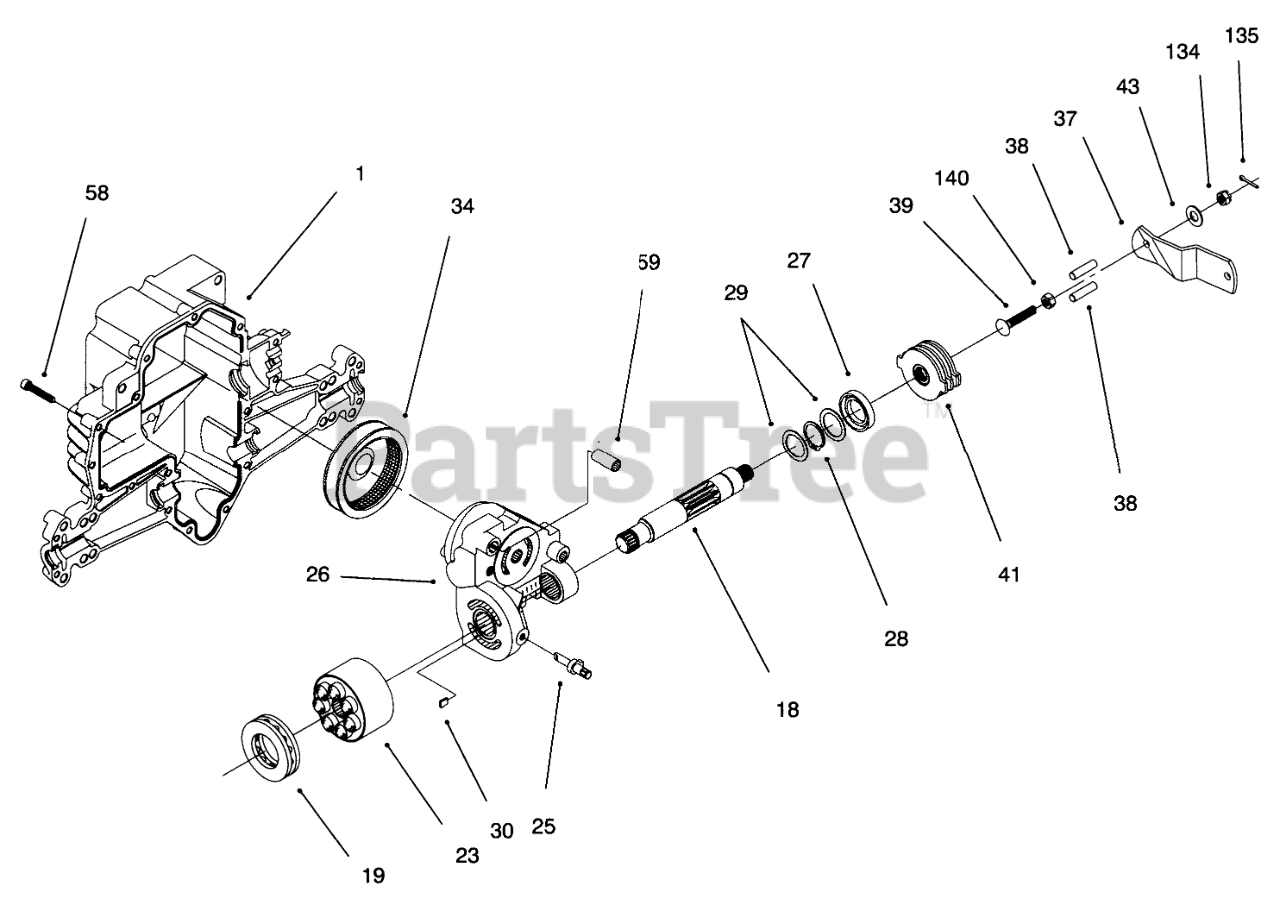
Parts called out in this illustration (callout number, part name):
1	HOUSING - LOWER
18	SHAFT - MOTOR
19	BEARING-THRUST
23	CYLINDER BLOCK ASM
25	ACTUATOR-BYPASS
26	ASM - CENTERSECTION
27	SEAL - LIP
28	RING - RETAINING
29	WASHER
30	PLATE-BYPASS
34	ELEMENT - OIL FILTER
37	LEVER - BRAKE
38	PIN - ACTUATING
39	BOLT 5/16-18 X 1-3/4
41	KIT-BRAKE ROTOR/STATOR
43	WASHER-PIVOT
134	NUT-CASTLE
135	PIN-COTTER
140	NUT-LOCK, NI
